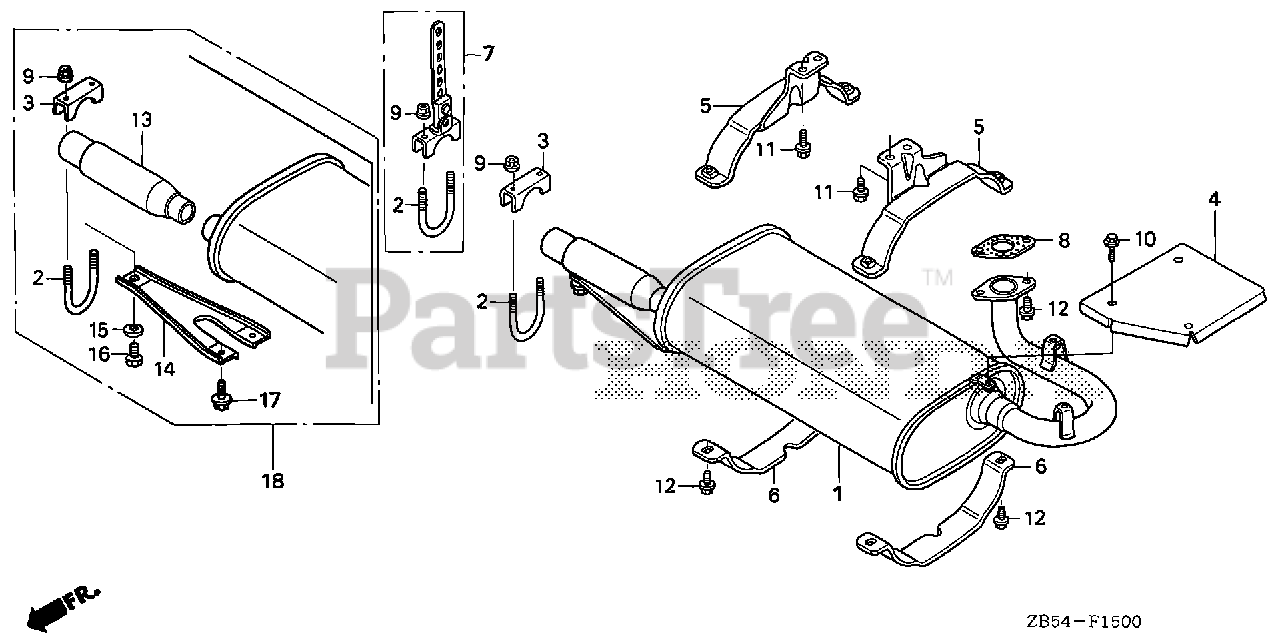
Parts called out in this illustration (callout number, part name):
1	MUFFLER
2	BOLT, MUFFLER TAIL PIPE
3	CLAMP, MUFFLER TAIL PIPE
4	PROTECTOR, EX. PIPE (NOT AVAILABLE)
5	STAY, MUFFLER
6	SUPPORT, MUFFLER
7	BRACKET ASSY., MUFFLER TAIL PIPE
8	GASKET, MUFFLER
9	NUT, FLANGE (8MM)
10	BOLT, FLANGE (6X12) Use up to Engine SN 1543277.
11	BOLT, FLANGE (8X16) Use from Engine SN 1000016.
12	BOLT, FLANGE (8X20) Use up to Engine SN 1609606.
13	ARRESTER, SPARK
14	BRACKET A, MUFFLER
15	WASHER, PLAIN (10MM)
16	BOLT, HEX. (10X12)
17	BOLT, FLANGE (6X12) Use up to Engine SN 1543277.
18	MUFFLER
